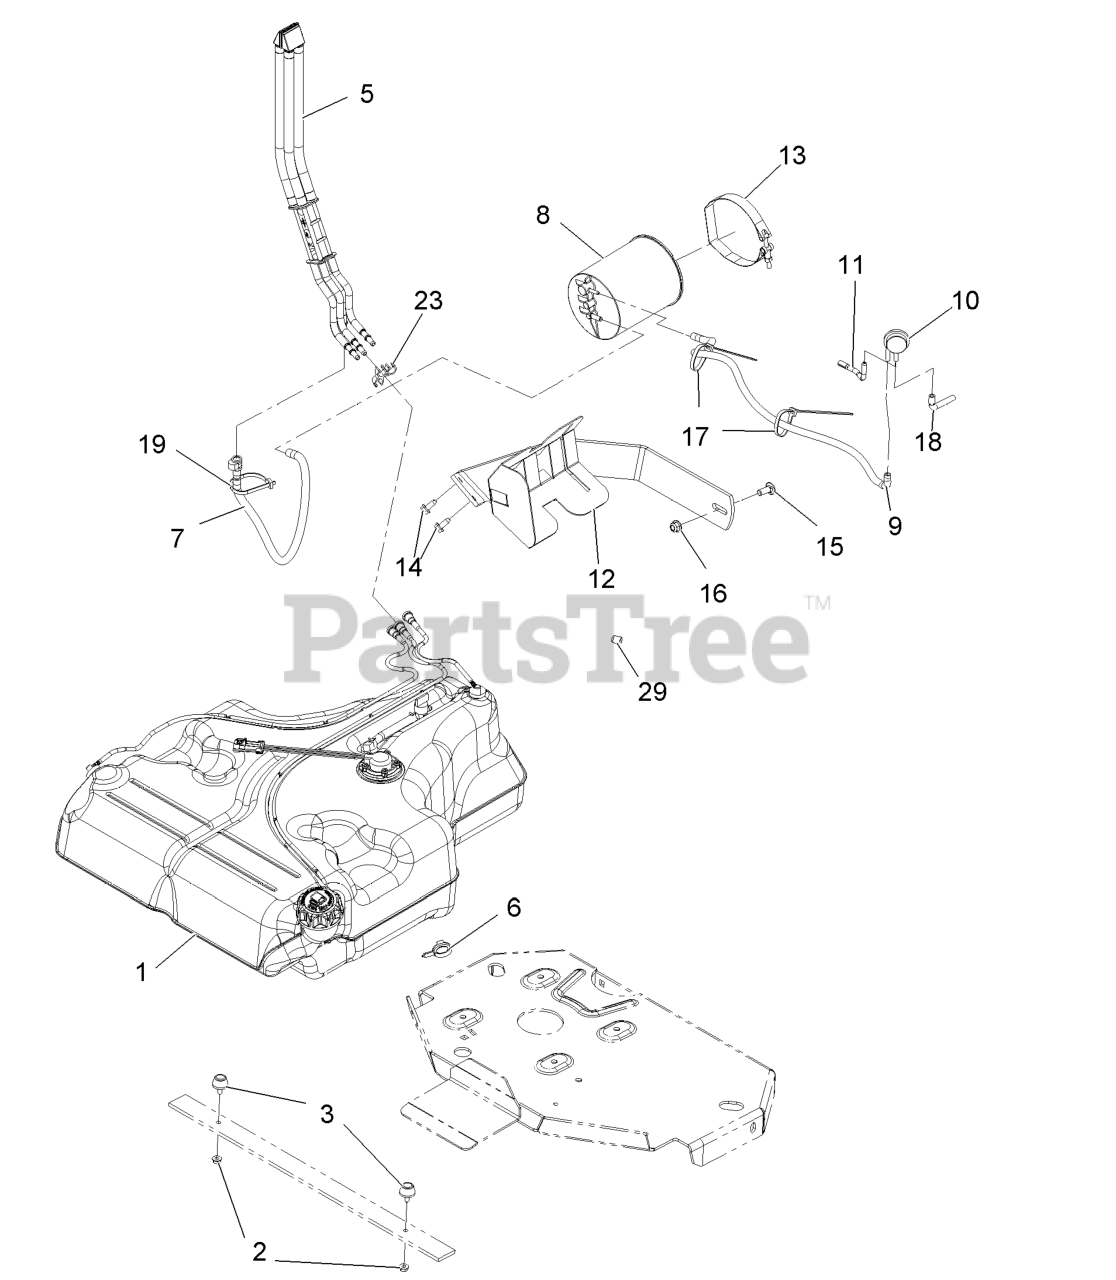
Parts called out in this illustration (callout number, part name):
3	BUMPER-RUBBER
5	FUEL MANIFOLD VENT ASM
6	CLAMP-HOSE
7	VENT HOSE ASM
8	CANISTER-CARBON, 1200CC
9	HOSE-VENT, FORMED
10	VALVE-CONTROL, VACUUM
11	HOSE-VENT, FORMED
12	MOUNT-CANISTER
13	CLAMP, T-BOLT
14	Screw-HWH 5/16-18 X 3/4 Tf
15	SCREW-CARR
16	NUT-HF, NI
17	TIE-PLASTIC
18	HOSE-VENT, FORMED
19	TIE-PLASTIC
23	CLIP-SPACER
29	PLUG-PORT
